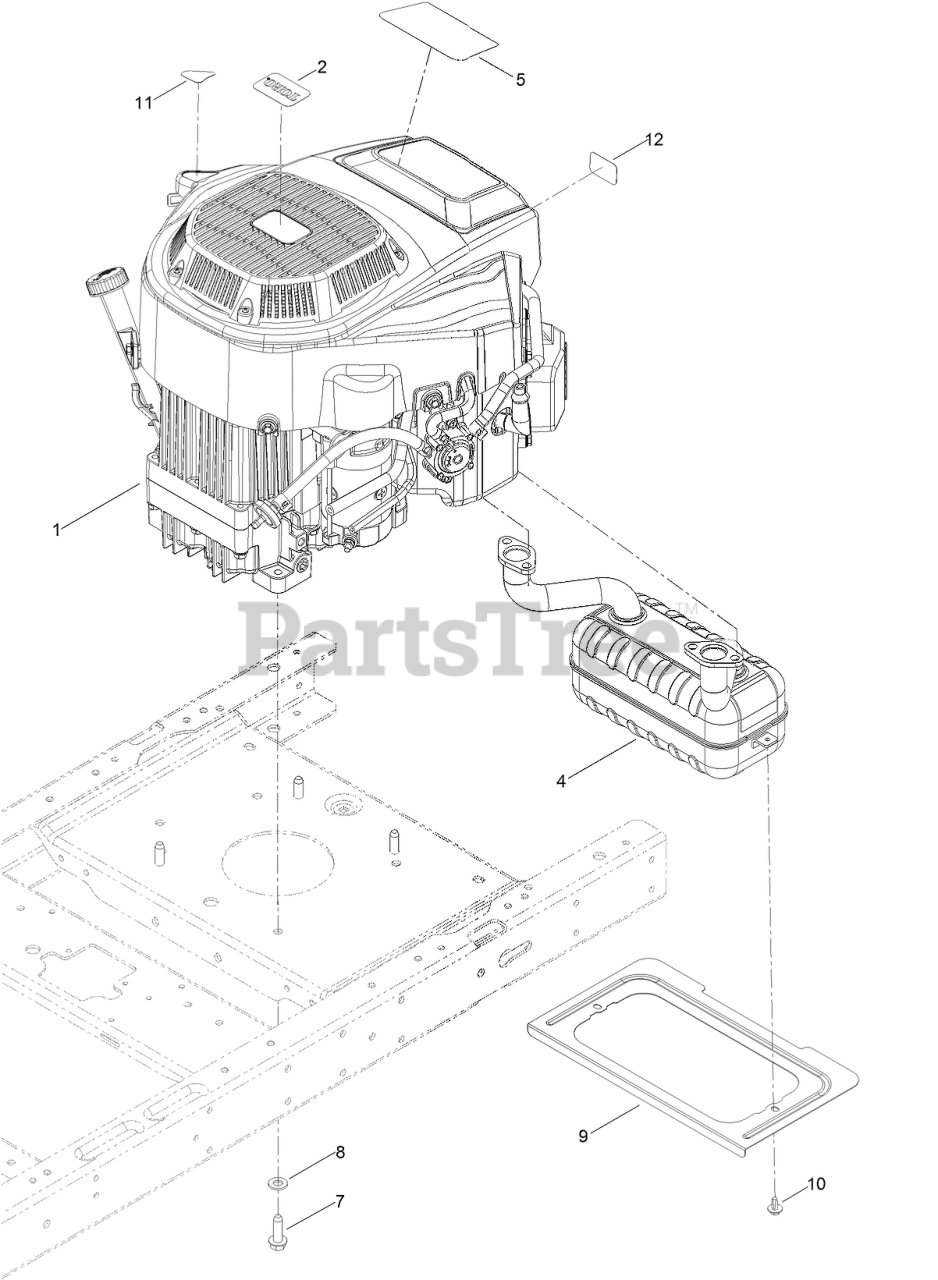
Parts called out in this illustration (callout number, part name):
1	ENGINE-2P77F
4	MUFFLER
5	DECAL-ENGINE HP
7	SCREW-TAPTITE
8	WASHER-FLAT
9	SHIELD-HEAT
10	SCREW-HHFTF
11	DECAL-DRAIN, OIL
12	PLACARD-INTAKE
